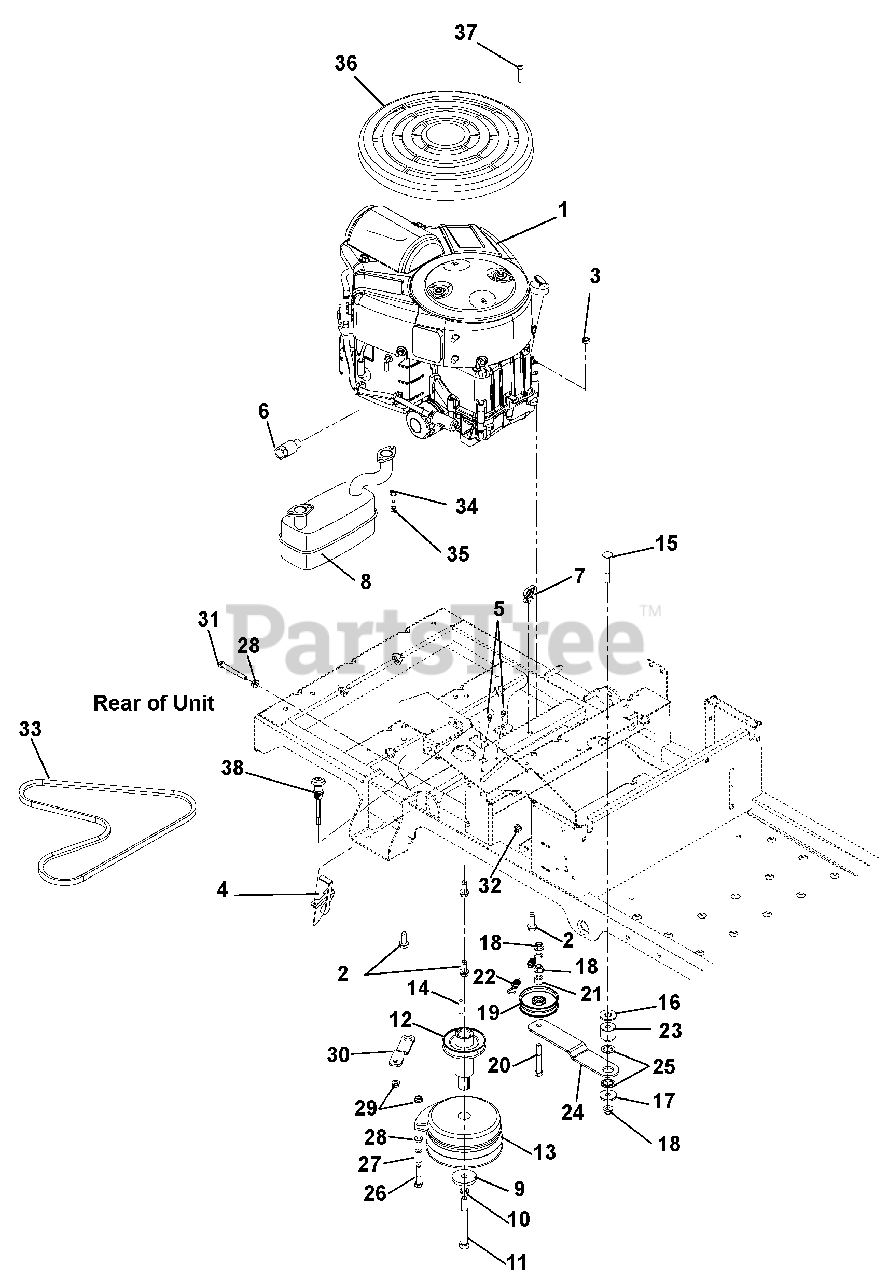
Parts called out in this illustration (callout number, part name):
1	ENGINE, 16HP V-TWIN CE
1	ENGINE, 18HP V-TWIN CE
2	@SCR-TAP .38-16X1.25 HWH TR YZ
3	@NUT-LK-CTR-JAM .375-16 YWZC
4	CABLE, THROTTLE
5	@SCR-TAP 10-24X.50 HWH TR YWZC
6	DRAIN, OIL
7	WIRE CLIP
8	MUFFLER - TWIN BRIGGS
9	WSHR-FL-STL .469X2.00X.25 YWZC
10	@WSHR-LK .44X.109 REG YWZC
11	BLT-HEX .44-20X4.50 GR8 YWZC
12	WMT-PTO EXTENSION W/SHEAVE
13	CLUTCH, 105 FT*LB MONO POLE
14	KEY-SQ .25 X 1.25 X .25 SAE
15	@BLT-RDHDSQNK .38-16X2.75 G5YZ
16	@WSHR-FL-STL.563X1.38X.109YWZC
17	WSHR-FL-STL .406X1.375X.135 YZ
18	@NUT-LK-NYL-FLG .38-16 YWZC
19	PULLEY, ENGINE CLUTCH 03608
20	@BLT-HEX .38-16X2.75 GR5 YWZC
21	BSHG-SLV .391X.688X.52 PM
22	SPRING, EXTENSION
23	SPACER, GROUND DRIVE IDLER
24	IDLER ARM, GROUND DRIVE
25	BUSHING, IDLER ARM
26	SCR-CAP .31-18X1 3/4 S/HD YWZC
27	SPACER, RUBBER 5/16 IDX1.0 LG
28	@NUT-SPNLK-FLG .312-18 YWZC
29	@NUT-LK-TOP-FLG .31-18 YWZC
30	BRKT, CLUTCH STOP
31	@BLT-HEX .31-18X2.75 GR5 YWZC
32	@NUT-LK-NYL-FLG .31-18 YWZC
33	V-BELT, HA-RAW EDGE
34	@WSHR-LK .31X.078 REG YWZC
35	SCR-CAP .31-18X.75 S/HD
36	GUARD, BRIGGS ENGINE
37	SCREW, 8-16X.87 PHPAN 3 LOBE
38	CABLE, CHOKE (SNAP IN)
